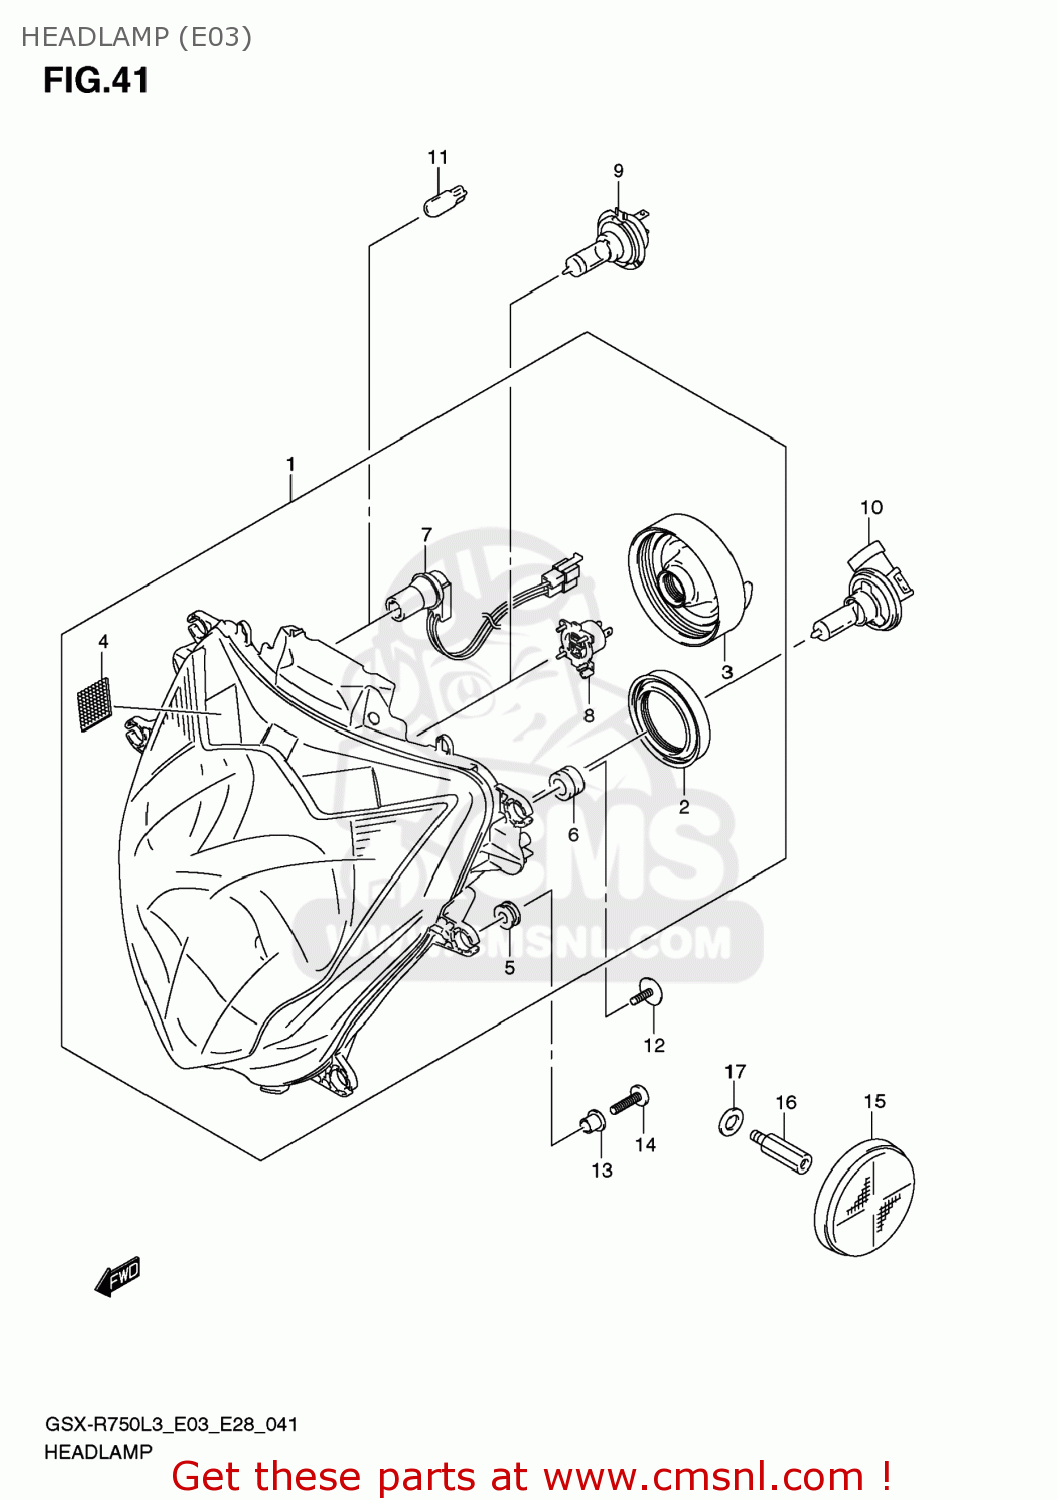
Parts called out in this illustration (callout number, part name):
1	HEADLAMP ASSY
2	COVER,SOCKET
3	COVER,SOCKET
4	FASTENER
5	CUSHION
6	CUSHION
7	CORD ASSY
8	ADAPTER ASSY
9	BULB(12V65W,H9)
10	BULB(12V55W/H7/PX26D/PHILIPS)
11	BULB(12V5W)
12	SCREW(5X15)
13	WASHER
14	SCREW
15	REFLEX REFLECTOR ASSY,FR SIDE
16	BOLT
17	WASHER(8.5X18X1)
